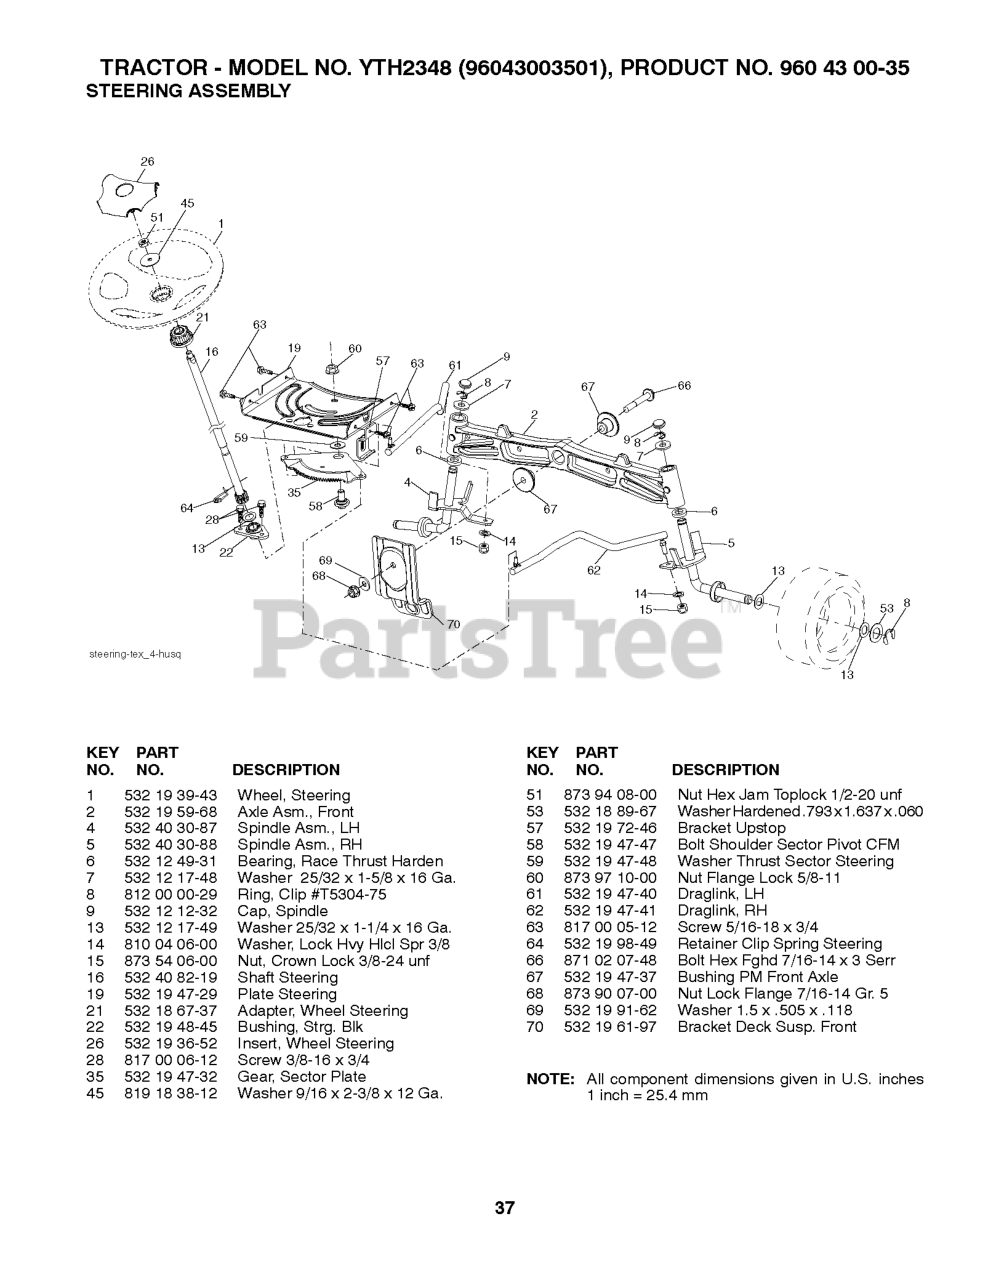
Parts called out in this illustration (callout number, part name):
1	WHEEL.STEERING.LEGEND2.GRY
2	AXLE.CAST.IRON
4	SPINDLE.WELDED.LH.15"TEX
5	SPINDLE.WELDED.RH.15"T
6	THRUST WASHER
9	CAP.SPINDLE.BLACK
14	WASHER, LOCK 3/8
15	NUT CROWNLOCK 3/8-24
16	SHAFT, STEERING
19	PLATE.STEER.DDL.NLT/NG
21	ADAPTER, WHEEL STNG..
22	BUSHING.ASM.STEERING.A
26	INSERT.CAP.STRG.WH.GRAY
28	SCREW, 3/8-16X3/4
35	GEAR.SECTOR.PLATE.DDL.
45	WASHER 9/16"ID, 2 3/8"OD
51	NUT.HEX.1/2-20
53	WASHER.HARDENED
57	BRKT.UPSTOP.GT/LT.TEX
58	BOLT.SHOULDER.SECTOR.P
59	WASHER.THURST.SECTOR.S
60	NUT FLANGE LOCK 5/8-11
61	DRAGLINK.LH.BALLSTUD.D
62	DRAGLINK.RH.BALLSTUD.D
63	SCREW
64	RETAINER.CLIP.SPRING.S
66	BOLT HEX FGHD 7/16-14 X 3 SERR
67	BUSHING.PM.FRONT AXLE
68	NUT.LOCK.FLANGE.7/16
69	WASHER.1.5X.505X.118
70	BRKT.DECK.SUSPENSION.F
